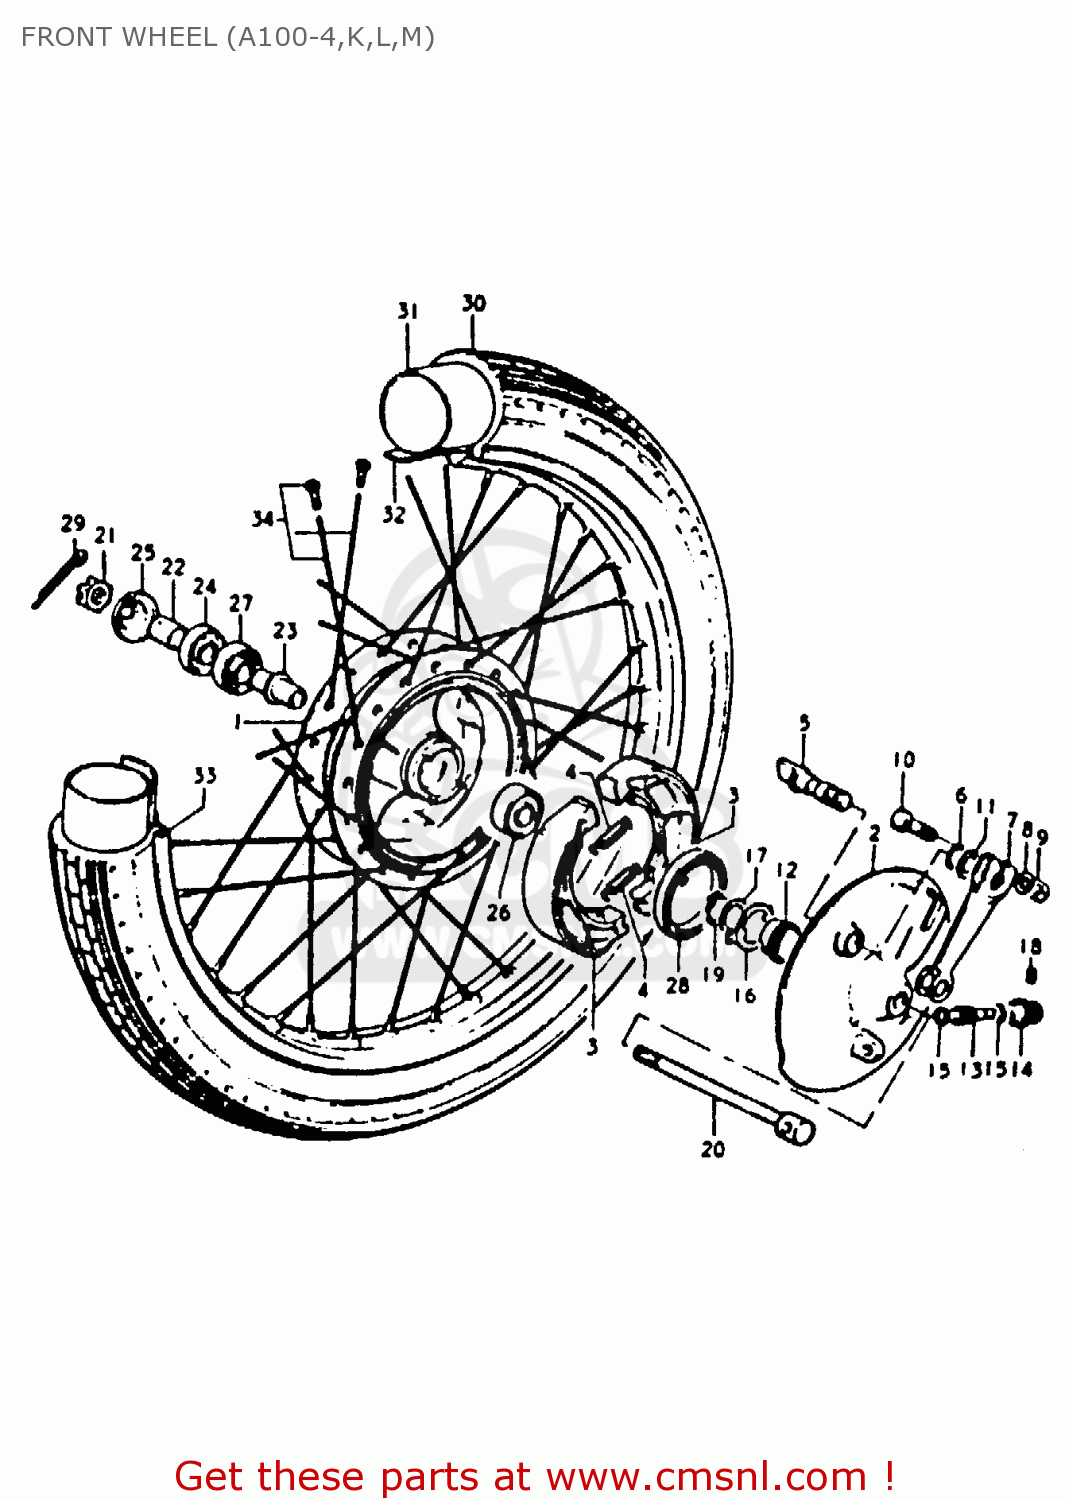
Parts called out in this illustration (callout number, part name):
1	HUB,FRONT
2	PANEL,FRONT BRAKE ANCHOR
3	SHOE,BRAKE
4	SPRING(L:34)
5	CAM,FR BRAKE
6	O RING(D:2.5,ID:11.4)
7	LEVER,FR BRAKE CAM
8	WASHER
9	NUT
10	BOLT
11	WASHER(12.5X20X1)
12	GEAR, SPEEDOMETER (NT:26)
13	PINION, SPEEDOMETER
14	BUSH,METER GEAR OUTER
15	WASHER (5.1X9X0.4)
16	DRIVER,SPEEDOMETER GEAR
17	WASHER(16X22X1)
18	SCREW
19	CIRCLIP,15MM
20	AXLE,FRONT
21	NUT
22	SPACER(10X15X12.4)
23	SPACER,FRONT HUB BEARING
24	SEAL,OIL(15X31X5)
25	COVER,FRONT HUB DUST S
26	BEARING, LH
27	BEARING
28	OIL SEAL (43X58X7)
29	COTTER PIN
30	TIRE,FRONT
31	TUBE,INNER
32	PROTECTOR,WHEEL,INNER
33	RIM,WHEEL(1.40X18)
34	SPOKE SET
